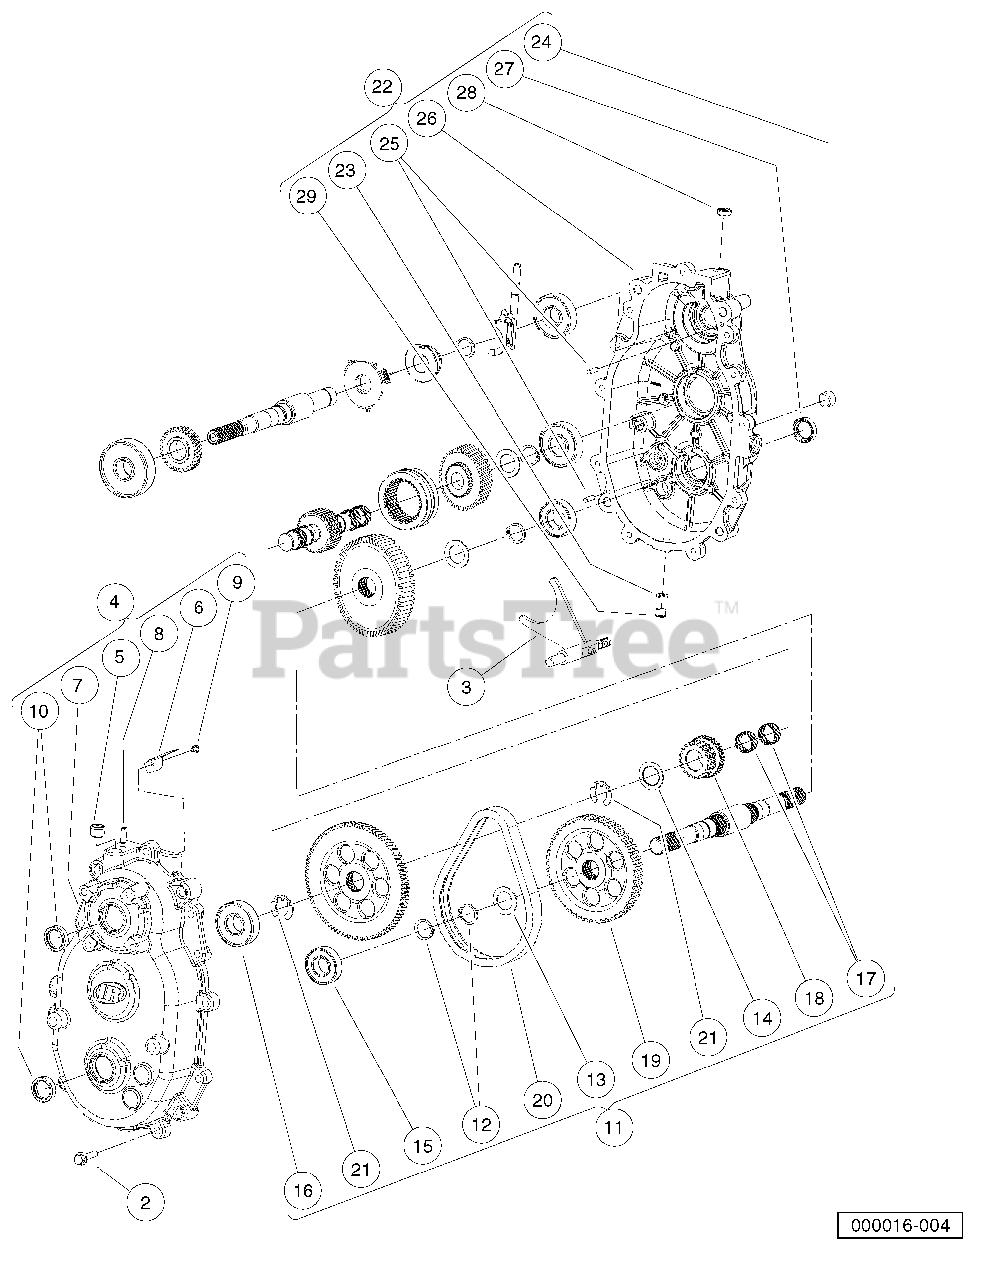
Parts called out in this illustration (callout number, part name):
1	Transmission, Parallel Shaft
2	Screw,hex Flange, M8 X 35
3	Fork, Transmission
4	Asm, Gear Case, Rear
5	Plug, Square Skt, 1/12-14, Ptf
6	Oil, Deflector
7	Gearcase, Rear
8	Vent, Trans
9	Screw, Tapping # 10-24 X .375
10	Seal, Triple, 25 X 35 X 7.8
11	Kit, Reverse Gear Repair
12	Ring, Retaining, Basic External
13	Washer, Thrust, 1.007 X .062
14	Washer, 26.231 X 39.167 X 1.57
15	Bearing, Ball
16	Bearing, Ball
17	Bearing, Needle
18	Sprocket, 19-Tooth
19	Sprocket, 51-Tooth
20	Chain, .375p, .75 Wide, 60ptch
21	Ring, Retaining, E-Ring
22	Asm, Case, Gear, Front
23	Washer, .625 X .382 X .60
24	Plug, Square Skt, 1/12-14, Ptf
25	Pin, Dowel, 6 X 20
26	Gearcase, Front
27	Seal, Triple, 25 X 35 X 7.8
28	Seal, Dual-Lip
29	Plug, 3/4-16
